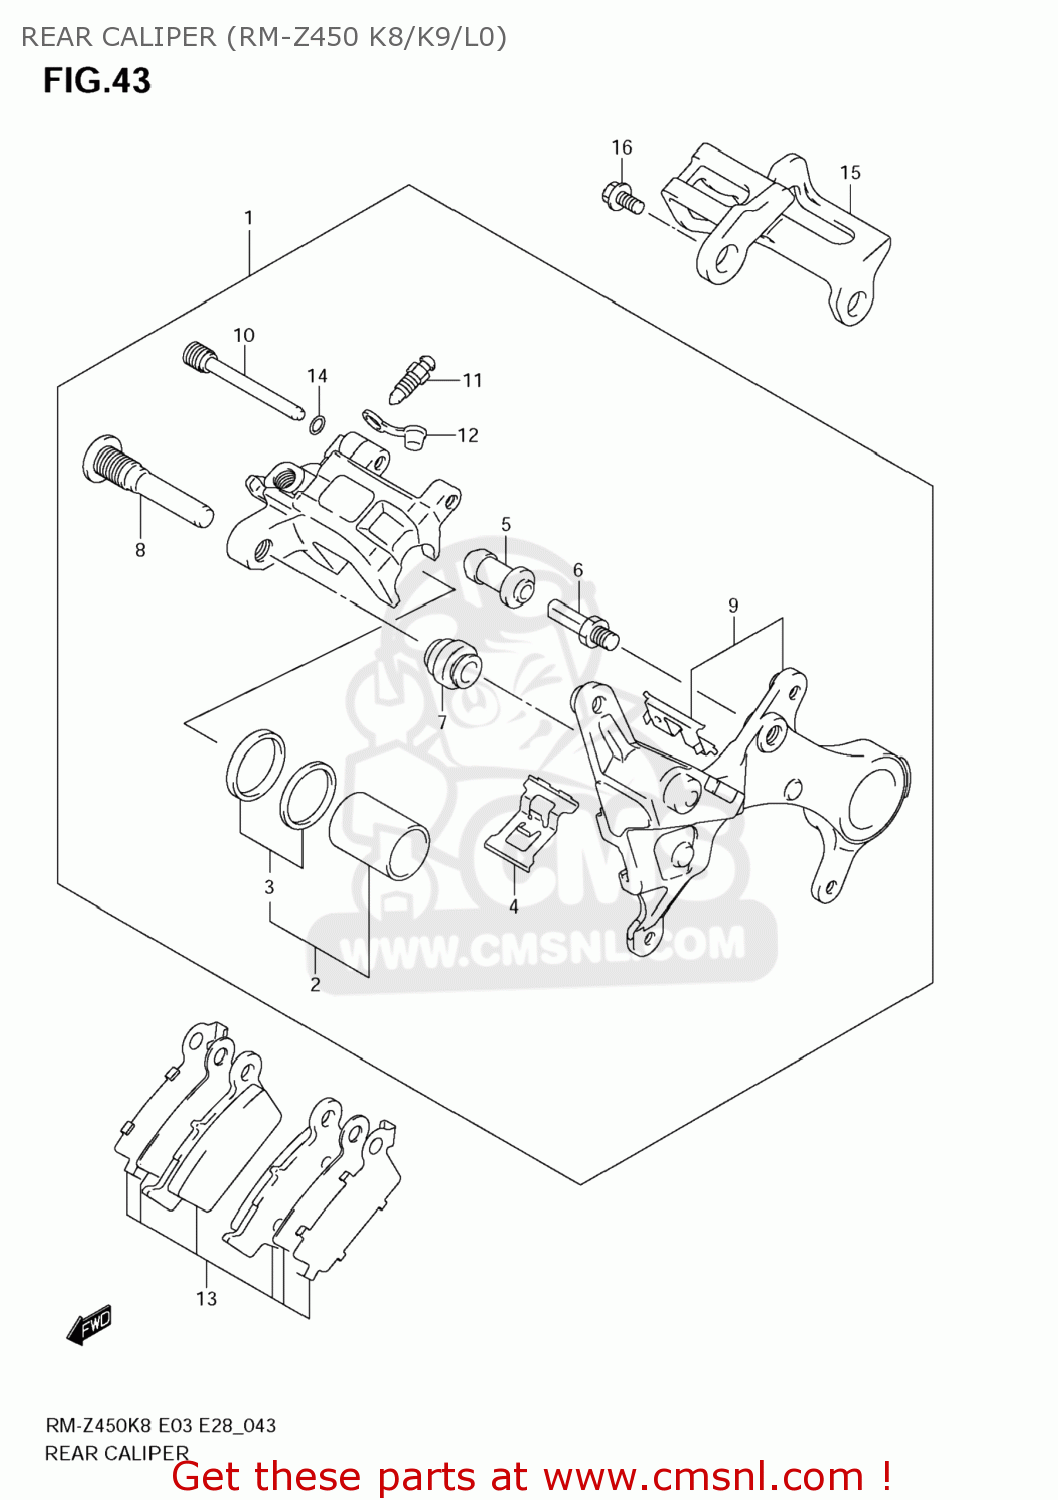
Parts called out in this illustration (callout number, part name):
1	CALIPER ASSY,RR
2	PISTON SET
3	SEAL SET,PISTON
4	SPRING,PAD
5	BOOT
6	PIN,BOLT
7	BOOT
8	PIN,BOLT
9	BRACKET,RR CALIPER
10	PIN,HANGER
11	BLEEDER
12	CAP,BLEEDER
13	PAD & SHIM SET (NAS)
14	RING,STOPPER
15	GUARD,RR CALIPER
16	BOLT(6X12)
